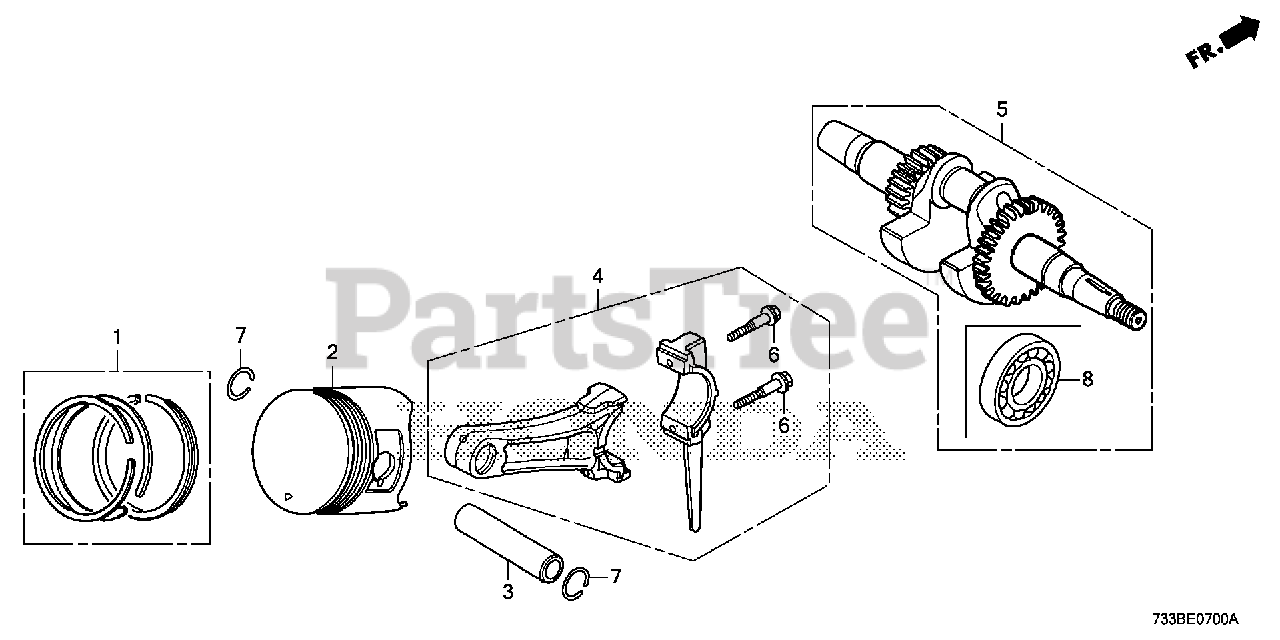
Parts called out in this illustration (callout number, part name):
1	RING SET, PISTON (STD) (TPR)
1	RING SET, PISTON (STD) (RIKEN) (NA USE ALT:13010-Z1T-931)
1	RING SET, PISTON (0.25) (TPR)
1	RING SET, PISTON (0.25) (RIKEN) (NA USE ALT:13011-Z1T-931)
1	RING SET, PISTON (0.50) (TPR)
1	RING SET, PISTON (0.50) (RIKEN) (NA USE ALT:13012-Z1T-931)
1	RING SET, PISTON (0.75) (TPR)
1	RING SET, PISTON (0.75) (RIKEN) (NA USE ALT:13013-Z1T-931)
2	PISTON (STD)
2	PISTON (0.25)
2	PISTON (0.50)
2	PISTON (0.75)
3	PIN, PISTON
4	ROD ASSY., CONNECTING (UNDER SIZE)
4	ROD ASSY., CONNECTING
5	CRANKSHAFT
6	BOLT, CONNECTING ROD (6X34.5)
7	CLIP, PISTON PIN (18MM)
8	BEARING, RADIAL BALL (6205) (NSK)
